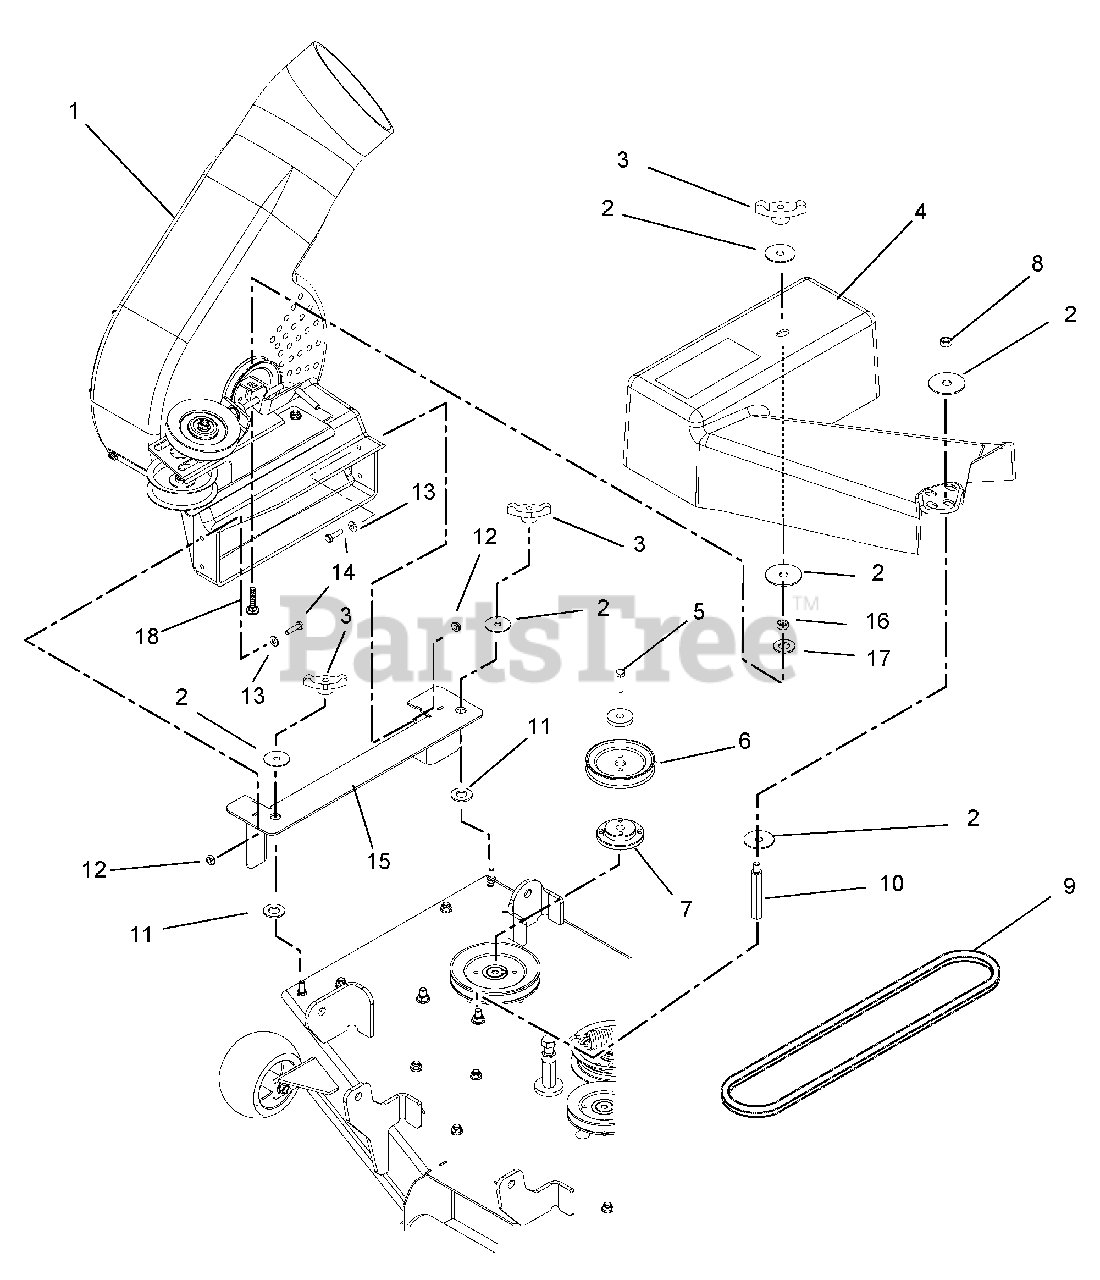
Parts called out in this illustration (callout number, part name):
1	Housing, Blower
2	Washer, Flat, Steel, .38 x 1.50 x .062
3	Knob, Wing, .312-18
4	Belt Cover, 42-Inch Decks
5	Bolt, Hex, .38-16 x 1.75 – Grade 8
6	Sheave, 4.00 Diameter
7	Assembly, Sheave Adapter
8	Nut, Locking, Center, .31-18
9	V-Belt, HA Wrapped
10	Standoff, 2.75 x 5/16-18
11	Washer, Flat, Steel, .656 x 1.25 x .10
12	Nut, Locking-Top-Flange, .25-20
13	Washer, Flat, Steel, .281 x .62 x .065
14	Bolt, Hex, .25-20 x 1.00 Grade 5
15	Bracket, Blower Weldment
16	Nut, Jam, .312-18
17	Washer, Flat Steel, .312 x .734 x .065
18	Bolt, Round Head Square Neck, .31-18 x 1.50
